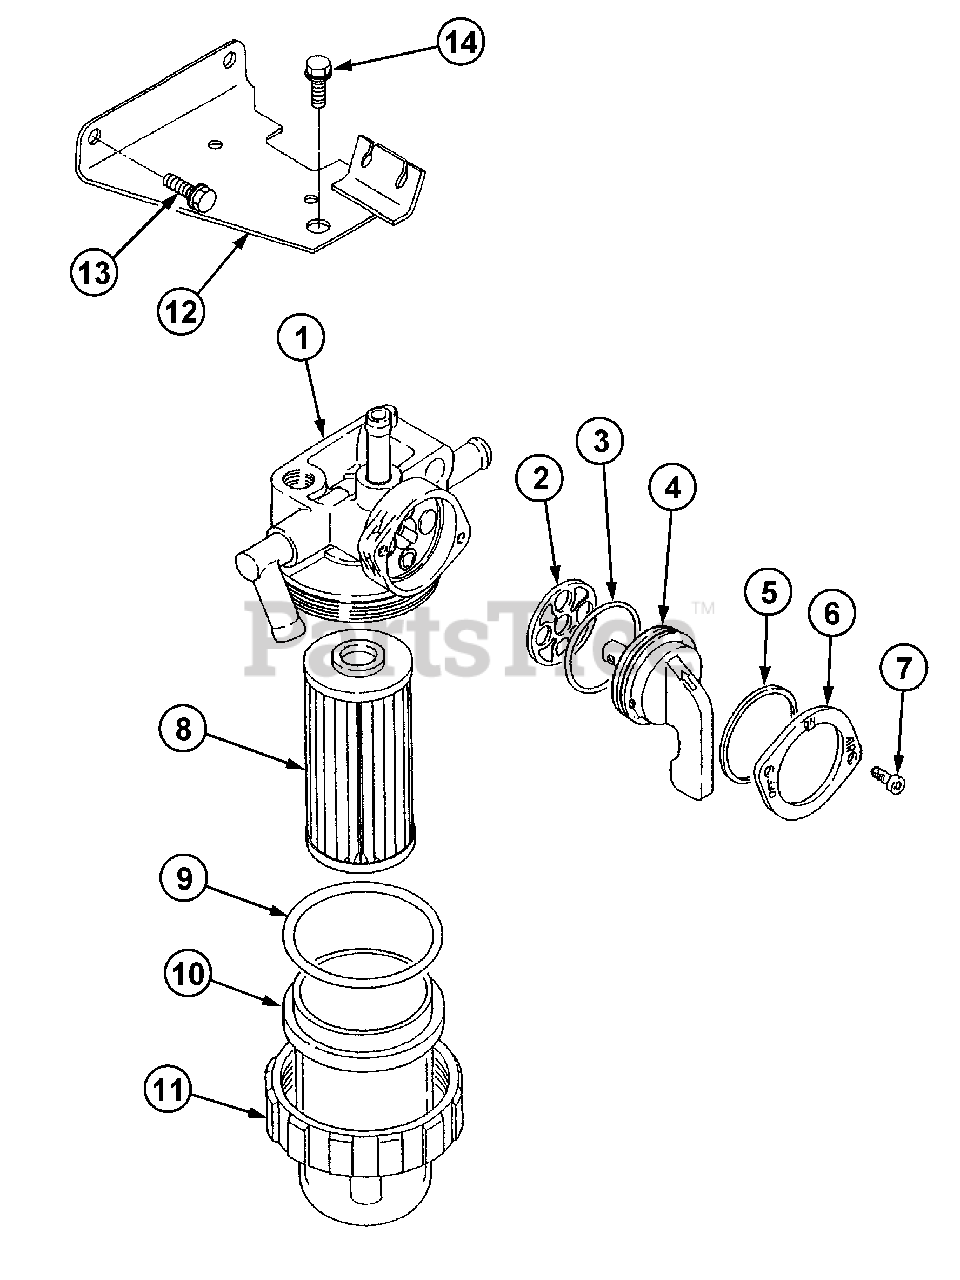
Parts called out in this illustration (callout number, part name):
1	Body Sub Assy
2	Packing, Valve
3	O-Ring, Valve
5	Washer, Wave
6	Plate, Lever
8	Element
9	O-Ring, Cup
10	Cup, Filter
12	Bracket, Filter
13	Bolt, w/Washer
14	Bolt, w/Washer
